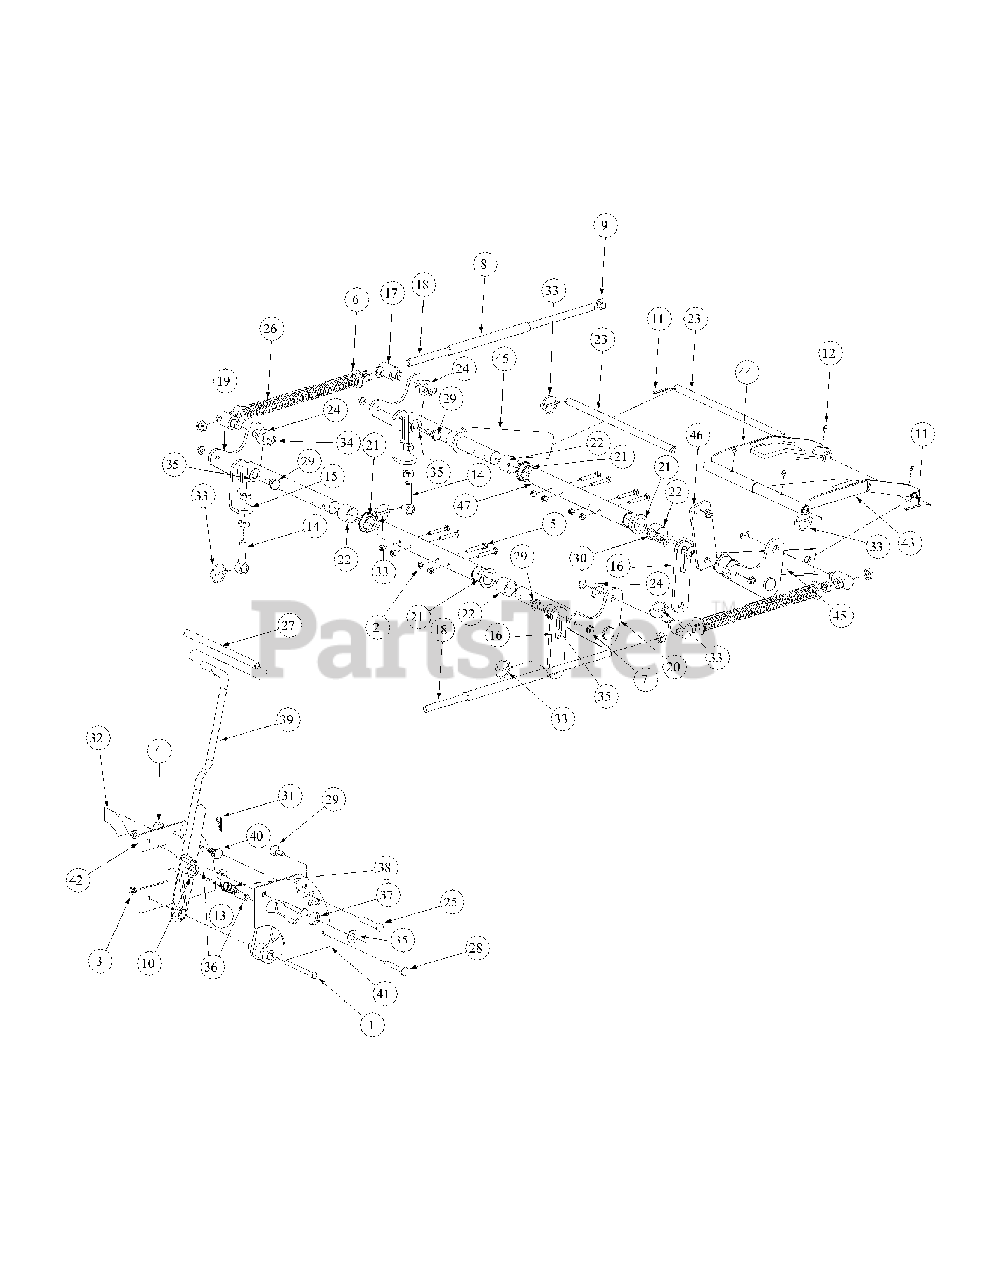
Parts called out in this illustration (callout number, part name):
1	Hex Cap Screw, 3/8-16, 3.75
2	Nut, 5/16-18, Nylock
3	Nylock Insert Lock Nut, 3/8-16
4	Nylock Insert Lock Nut, 1/2-13
5	Hex Cap Screw, 5/16-18 x 2
6	Flat Washer, 5/8
7	Hex Nut, Flange Lock, 3/8-16
8	Hose, 5/8 ID 13/16 OD, 8" LG
9	Jam Nut, 5/8-11
10	Flat Washer, .06, .776, 1.25
11	Cotter Pin, 3/16 x 1-1
12	Grease Fitting, 1/4-28 x 3/16
13	Idler Washer
14	Eye Bolt, 5/8ID
15	Eye Bolt Mount Link, 5/8 ID
16	Deck Link
17	Ferule Lift
18	Lift Connector Rod
19	Bellecrank Weldment Lift, Left Hand
20	Bellecrank Weldment Lift, Right Hand
21	Hex Flange Bearing, 1.25 ID
22	Frame Lift Spacer
23	Front Lift Link, Rod Mount
24	Spacer, .812 ID x .268 Lg.
25	Clevis Pin, .500 Dia. x 2.625 Lg.
26	Lift Compression Spring
27	Lift Handle Grip
28	Carriage Bolt, 3/8-16, 2.75
29	Shoulder Screw, 0.625 OD x .437 Lg.
30	Shoulder Screw, 0.625 OD x .830 Lg.
31	Cotter Pin, .148 x 3.00
32	Decal Height Indicator
33	Linch Pin, 3/16 Dia.
34	E Clip, 3/4 Dia.
35	Nylon Flat Washer, 5/8
36	Spacer, .39 ID x .63 OD x 1.442
37	Lift Pivot Assembly
38	Lift Handle Spring
39	Lift Handle Assembly
40	Shoulder Screw, 5/8 OD x 0.264
41	Outer Lift Index Plate
42	Inner Lift Index Plate
43	Bearing Lift Brace Assembly, Right Hand
44	Bearing Lift Brace Assembly, Left Hand
45	Front Frame Strut Assembly
46	Lift Link Adjustment
47	Lift Shaft Holder
